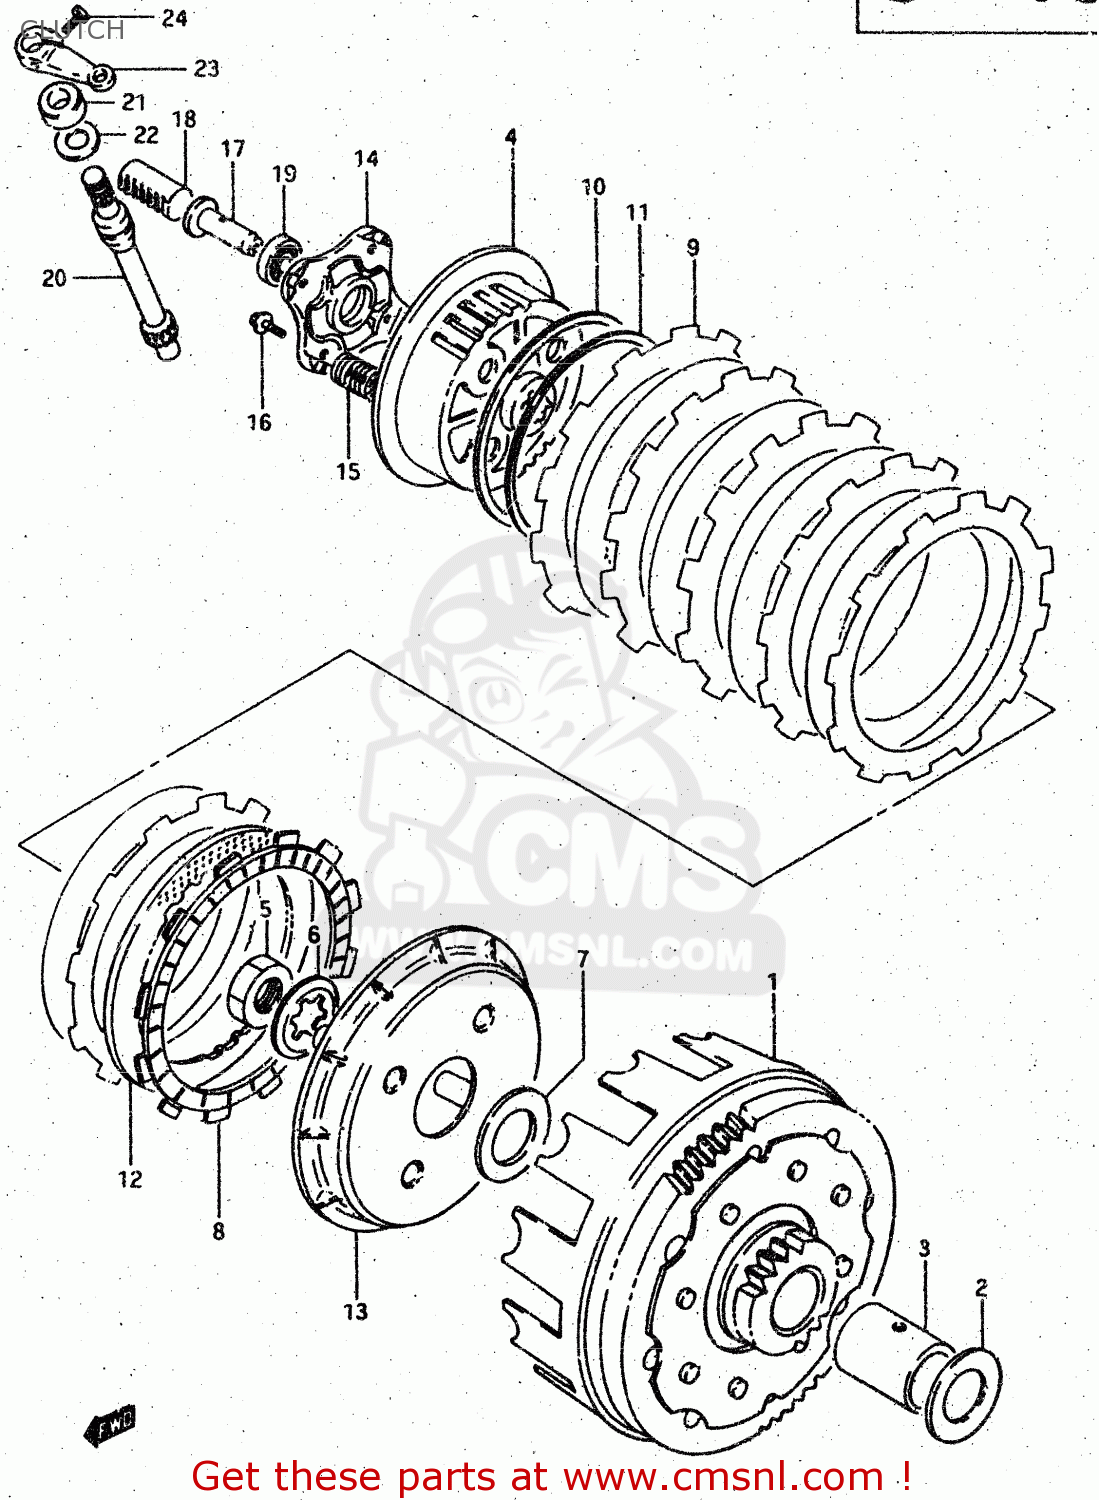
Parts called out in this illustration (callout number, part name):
1	GEAR ASSEMBLY,PRIMARY DRIVE
2	WASHER
3	SPACER(22X28X32.5)
4	HUB,CLUTCH SLEEVE
5	NUT
6	WASHER,LOCK
7	WASHER
8	PLATE,CLUTCH DRIVE (NAS)
9	PLATE,CLUTCH DRIVE(T:3.5) (NAS)
10	SEAT,WAVE WASHER(T:1.4)
11	WASHER
12	PLATE,CLUTCH DRIVEN(T:1.6) (NAS)
13	DISC,CLUTCH PRESSURE
14	PLATE,RELEASE
15	SPRING
16	BOLT 6X20
17	PIECE,CLUTCH PUSH
18	RACK,CLUTCH RELEASE
19	BEARING
20	PINION,CLUTCH RELEASE
21	SEAL,OIL (12X22X9)
22	WASHER (14.2X22X1)
23	ARM,CLUTCH RELEASE
24	BOLT
